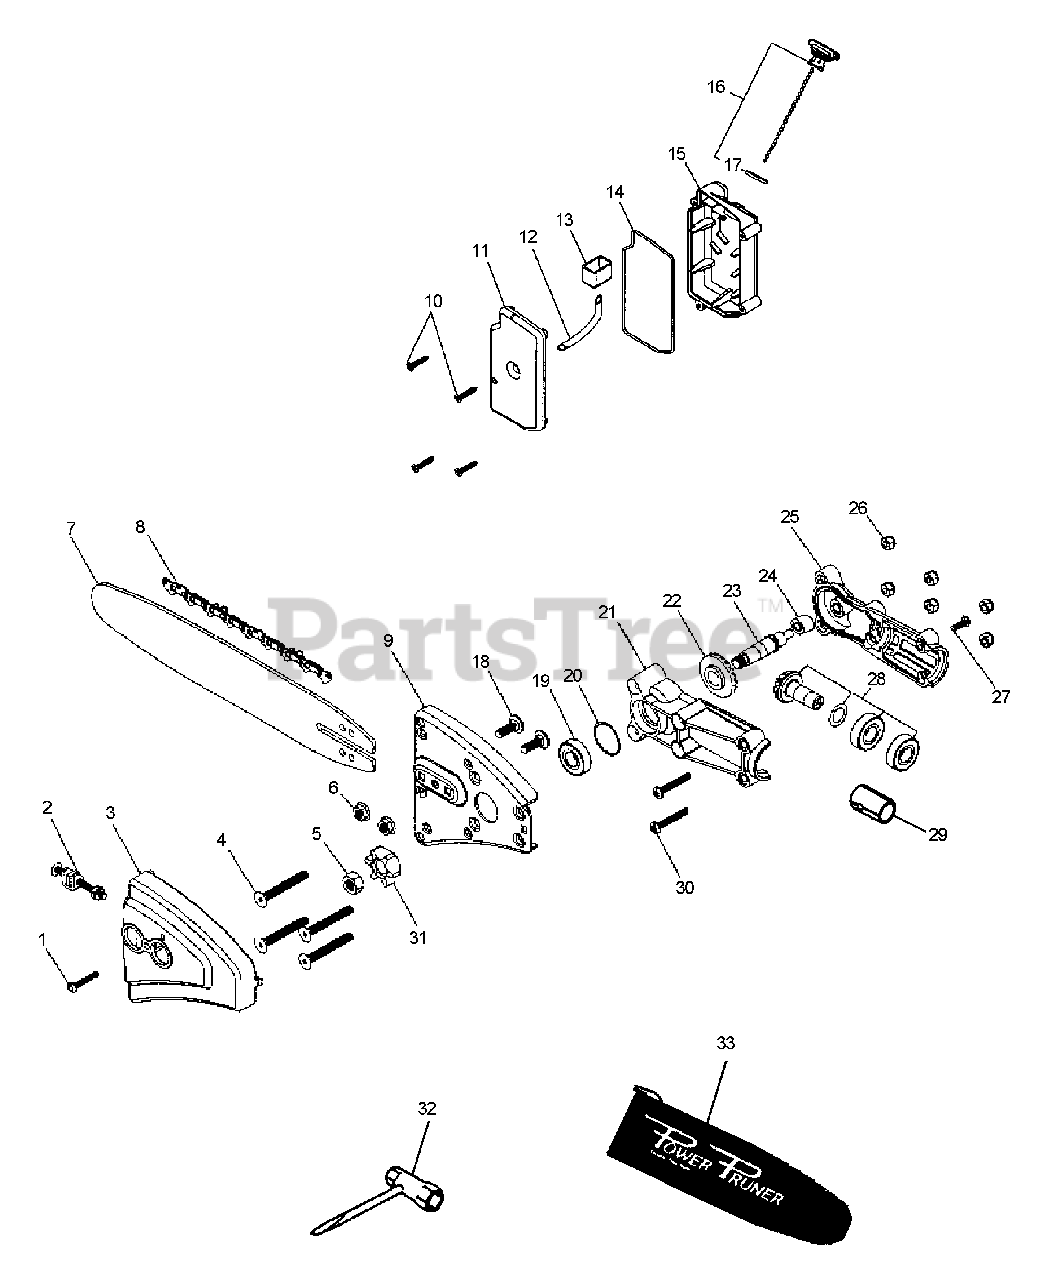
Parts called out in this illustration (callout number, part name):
1	SCREW - 8-32 X 1"
2	TENSIONER KIT
3	GUARD, SPROCKET
6	NUT - FLANGE
7	GUIDE BAR - 10" (25cm)
8	SAW CHAIN - 10" (25cm)
9	SAW BAR CARRIER
10	SCREW
11	TANK, OIL (CHAIN SIDE)
12	PIPE - 3X5X70 -- BLACK
13	CUP, OIL
15	TANK, OIL (CAP SIDE)
16	CAP ASSY
18	BOLT
19	BEARING, BALL - 6001 DDU
20	SHIM .004"
21	CASE, GEAR - RIGHT
22	GEAR - BEVEL
23	SHAFT GEAR ASSY
24	GUIDE, DRIVESHAFT
25	CASE, GEAR - RIGHT
26	LOCKNUT - 10-24
27	SCREW
28	SHAFT GEAR ASSY
29	COLLAR - 22
30	SCREW - 10-24 X 1-1/4"
31	SPROCKET
32	T-WRENCH
33	COVER, GUIDE BAR
